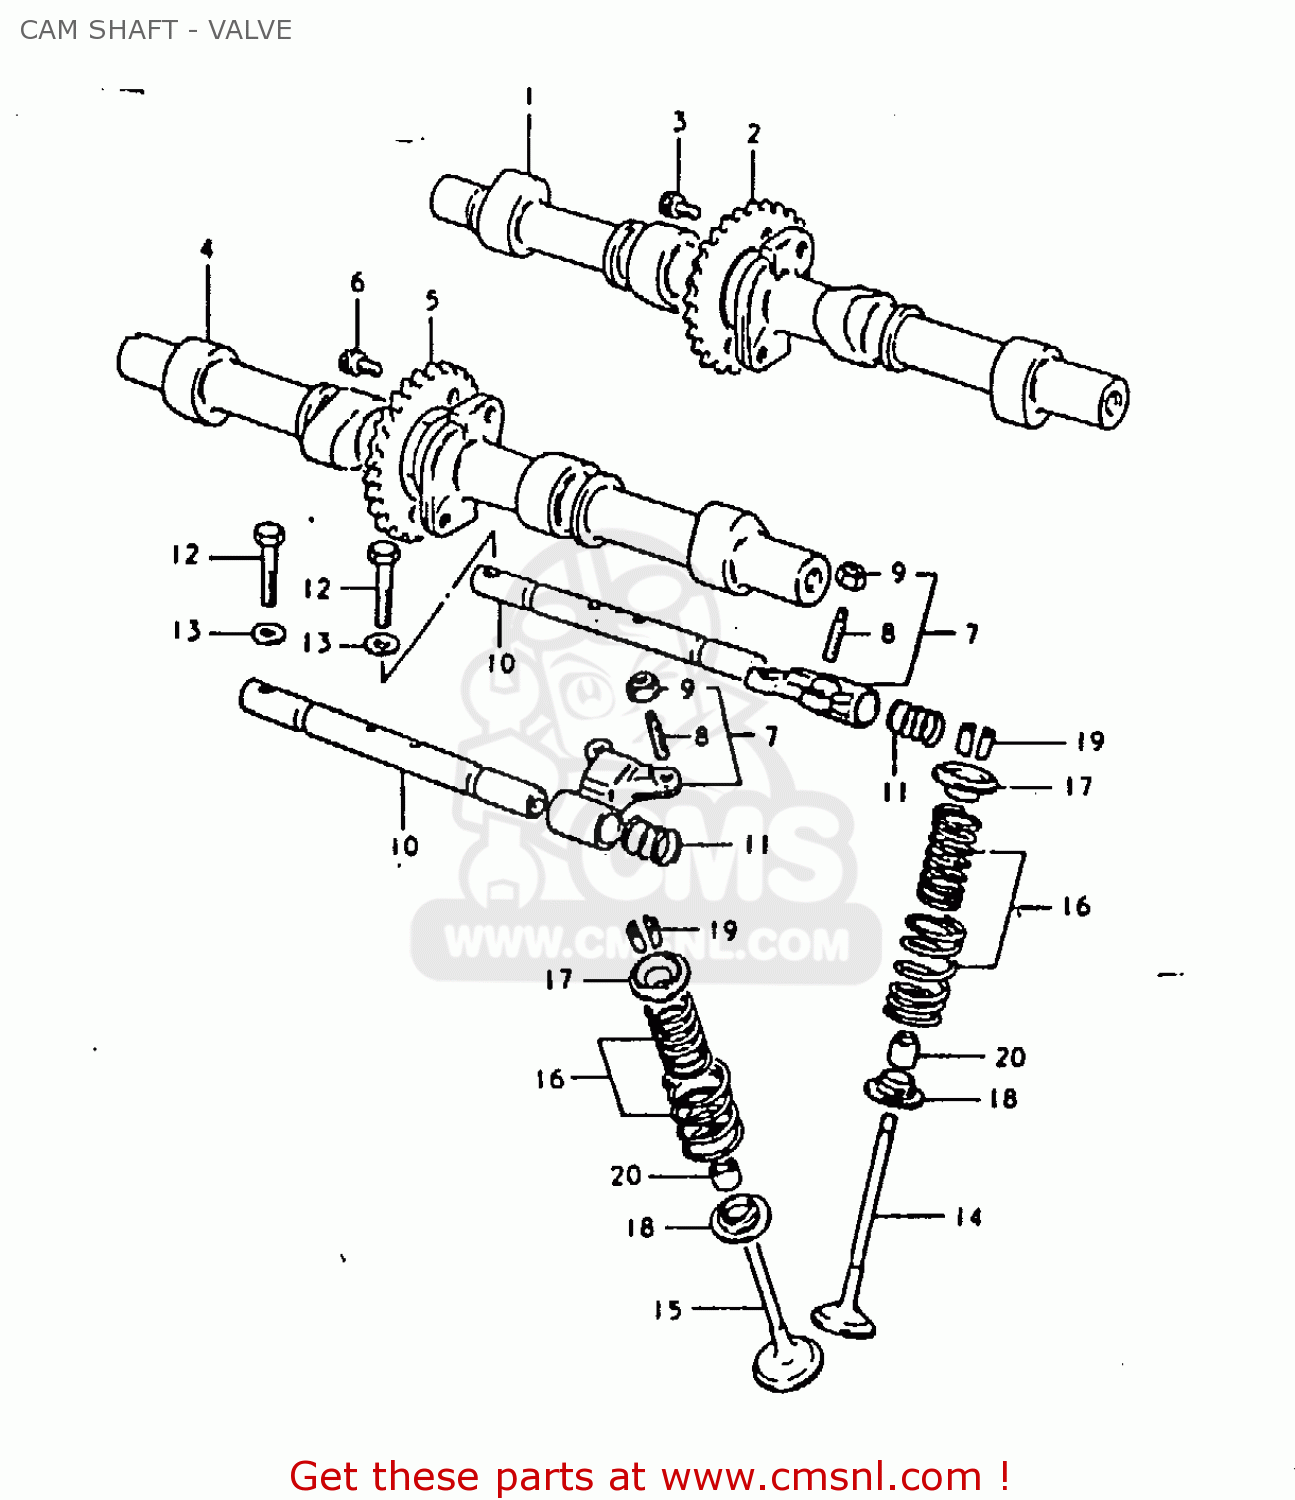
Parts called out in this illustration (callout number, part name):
1	CAMSHAFT
2	SPROCKET,CAMSHAFT
3	BOLT 6X11
4	CAMSHAFT,EXHAUST
5	SPROCKET,EXHAUST CAMSHAFT
6	BOLT 6X11
7	ARM,VALVE ROCKER
8	SCREW,TAPPET ADJUSTING
9	NUT,ADJUSTING
10	SHAFT,VALVE ROCKER
11	SPRING
12	BOLT
13	WASHER
14	VALVE,INTAKE
15	VALVE,EXHAUST
16	SHIM,TAPPET
17	RETAINER,VALVE SPRING
18	SEAT,VALVE SPRING
19	COTTER VALVE
20	OIL SEAL
